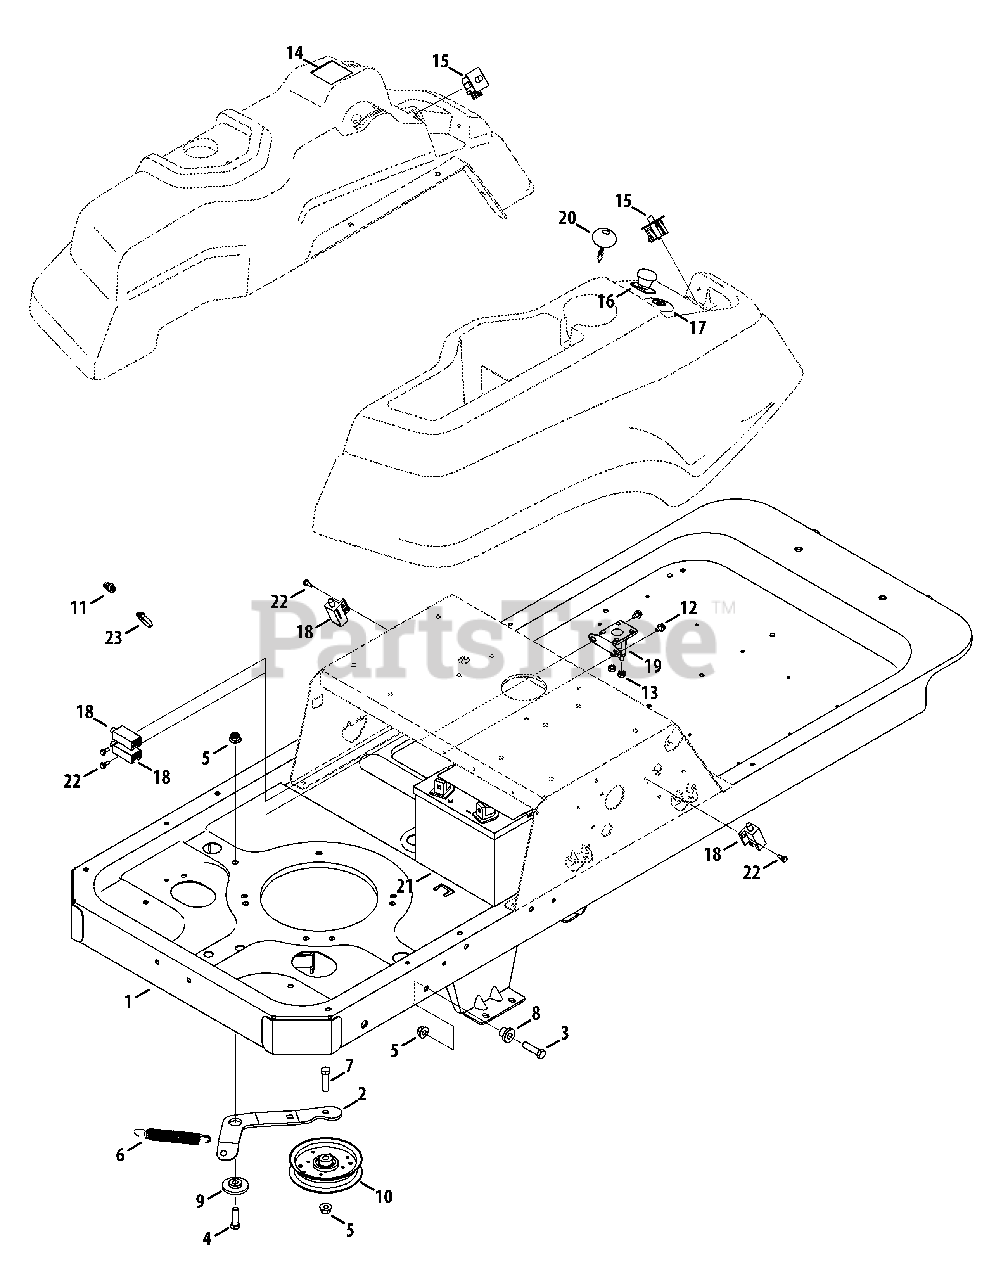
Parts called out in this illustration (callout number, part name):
1	Frame Assembly
3	Hex Screw, 3/8-16 x 1.5
4	Hex Screw, 3/8-16 x 1.25
5	Flange Nut, 3/8-16
6	Extension Spring, .75 x 5.06
7	Hex Screw, 3/8-16 x 1.5
8	Shoulder Spacer, .39 x 1.0 x .7
9	Shoulder Spacer, .884 x .19
10	Idler Pulley, 4.25 Dia.
11	Wire Harness
12	Hex Screw, 1/4-20 x .375
13	Hex Nut, 1/4-20
15	Neutral Switch
16	PTO Switch
17	Ignition Switch
18	Interlock Switch
19	Solenoid
20	Key
22	Shoulder Screw, #10-32 x .500
23	Cable Tie
